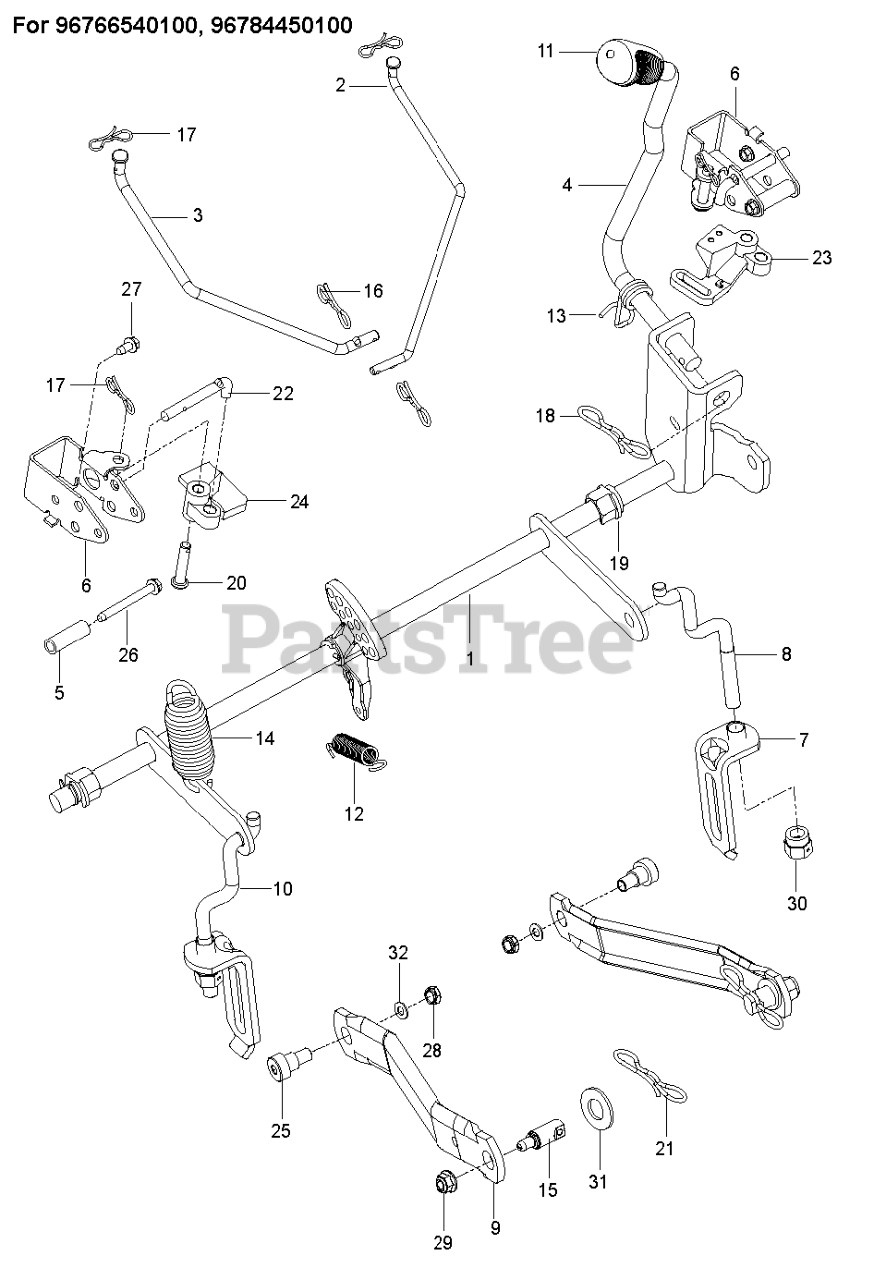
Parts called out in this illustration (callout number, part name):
1	SHAFT.ASM.RZ.DECK.LIFT.SRV
2	LINK.BRAKE.PARK.UPPER.LH
3	LINK.BRAKE.PARK.UPPER.RH
4	LIFT.LEVER.ASM.RZ.SERVICE
5	SPACER.334.ID.5.OD.1.5.L
6	BRACKET.BELLCRANK.PBRAKE X431
7	ASSEMBLY, BRKT LINK
8	LINK, REAR SUSPENSION
9	ARM.RFIXED.MOWER.SUSPNSIONX431
10	LINK.ASM.RZ.LIFT.SERVICE
11	GRIP.HANDLE.LIFT.PVC.428
12	RETURN.BRAKE.PARK.AUTO
13	SPRING.TORSION.LIFT.HANDLE
15	STUD.FASTNER.W/ANTI-ROTATE
16	PIN.COTTER.5/16.BOW TI
17	PIN COTTER;LOCKING;BOWTIE;1IN
18	PIN.COTTER.7/16.BOW TI.
19	PLASTIC NUT
20	PIN.5.16X1.5
21	PIN.COTTER.7/16.BOW TI.
22	ROD.PUSH.BRAKE
23	BELLCRANK.LH
24	BELLCRANK.RH
25	SB 3/8-16 X 3/8 SKT HD ZD
26	SCREW THD;ROLL;1/4-20 X 2.25
27	SCREW.1/4-20X5/8
28	NUT HEX 3/8-16 NYLON, THIN
29	5/16-18 NYLOC FLANGE NUT
30	NUT, LIFT LINK 7/16-20
31	WASHER
32	WASHER
